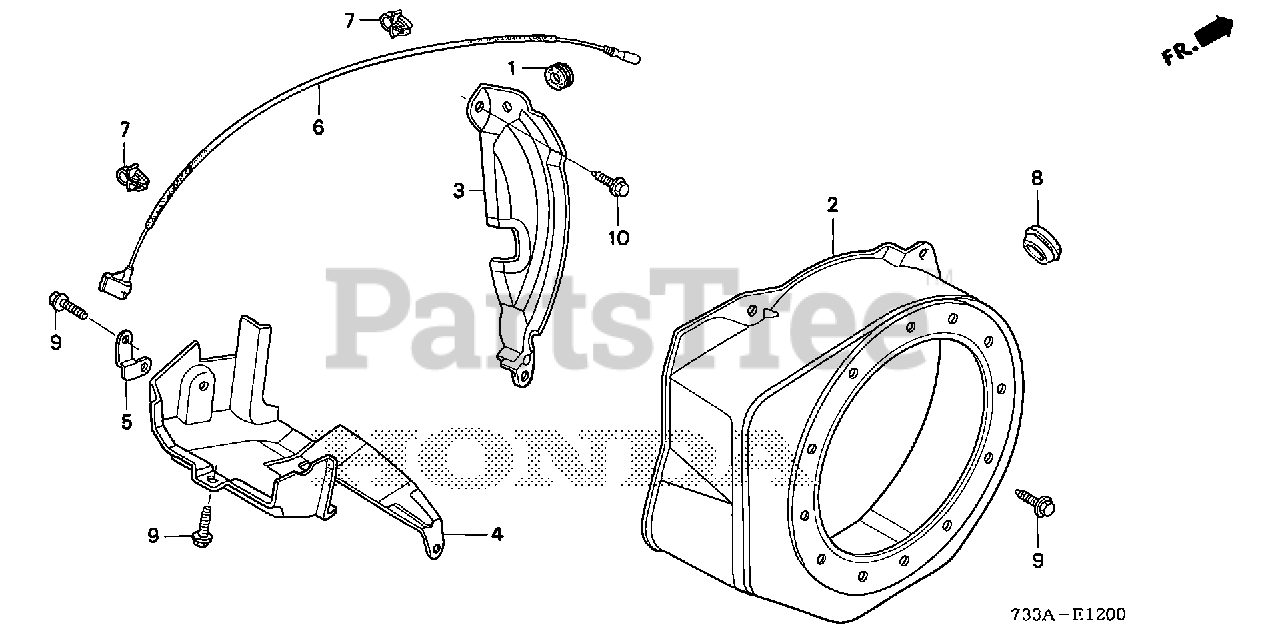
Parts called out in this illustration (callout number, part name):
2	COVER, FAN *R280* (POWER RED)
3	PLATE, SIDE (STD)
5	STAY, WIRE CLIP
6	WIRE, STOP SWITCH (395MM)
6	WIRE, STOP SWITCH (370MM)
7	HOLDER, STOP SWITCH WIRE
8	GROMMET, DRAIN HOLE
9	BOLT, FLANGE (6X12) (CT200)
10	BOLT, FLANGE (6X20) (CT200)
